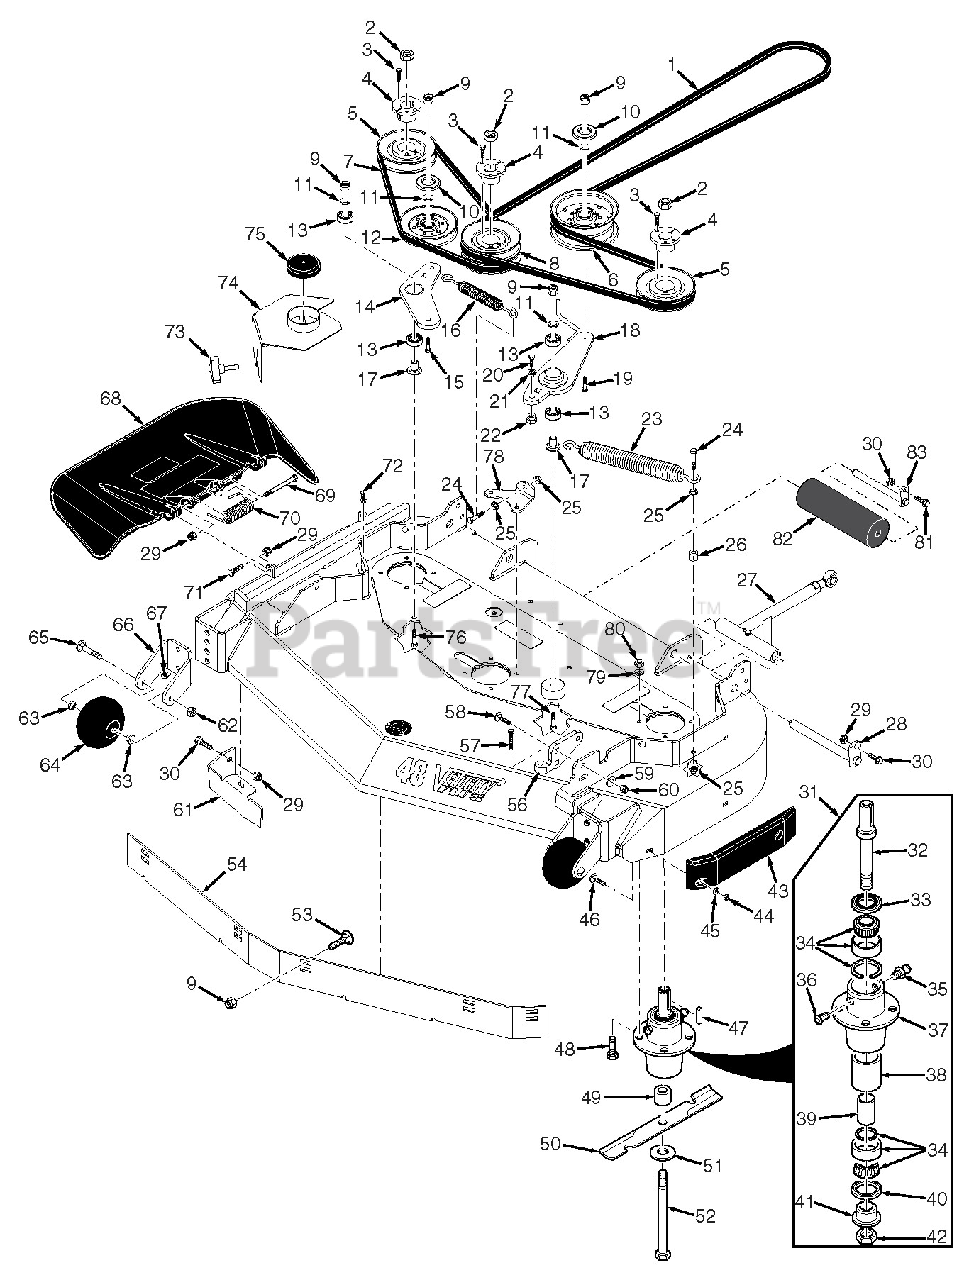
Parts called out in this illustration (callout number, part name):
1	Belt, Deck Drive
2	Nut, 5/8-11 UNC
3	Bolt, Hex Head 1/4-20 x 1"
4	Tapered Hub, 1.125" Bore
5	Pulley, 5.13" Dia.
5	Pulley, 5.73" Dia.
6	Pulley, 5" Idler
7	Belt, RH Deck Drive
8	Pulley, 5.232" Dia.
8	Pulley, 5.832" Dia.
9	Nut, Elastic Stop 3/8-16
10	Dust Shield
11	Flatwasher, 3/8-.391 x .938 x .105 HD
12	Pulley, Idler
13	Bearing
14	Idler Arm Assy.
15	Bolt, Hex Head 3/8-16 x 2"
16	Spring, RH Deck
17	Pivot, Idler
18	Idler Arm Assy.
19	Bolt, Hex Head 3/8-16 x 3"
20	Bolt, Hex Head 7/16-14 x 1"
21	Lockwasher, 7/16" Spring
22	Boss, Spring Anchor - LH
23	Spring, LH Deck
24	Bolt, Hex Head 3/8-16 x 1-1/2" Grade 8
25	Nut, Serrated Flange 3/8-16
26	Spacer
27	Pusharm Assy., LH
27	Pusharm Assy., RH
28	Rod Weldment, Pusharm
29	Nut, Elastic Stop 5/16-18
30	Bolt, Hex Head 5/16-18 x 1"
31	Spindle Assembly
32	Shaft, Spindle
33	Seal, Top
34	Bearing Assembly
35	Grease Fitting
36	Relief Fitting, Spindle
37	Spindle Housing
38	Spacer, Outside
39	Spacer, Inside
40	Seal, Bottom
41	Spindle Bushing
42	Nut, Special 1-1/16 - 18
43	Wear Pad
44	Nut, Center Lock 5/16-18
45	Flatwasher, 5/16-.344 x .688 x .065
46	Bolt, Carriage 5/16-18 x 3/4"
47	Key, 1/4 x 1/4 x 2"
48	Bolt, Hex Head 5/16-18 x 1-3/4" Grade 8
49	Spacer, Spindle Bottom
50	Cutter Blade, 16.5"
50	Cutter Blade, 18"
51	Flatwasher, 5/8-.688 x 1.75 x .134 HD
52	Bolt, Hex Head 5/8-11 x 9-1/2"
53	Bolt, Carriage 3/8-16 x 1"
54	Baffle, Flange - 48V
54	Baffle, Flange - 52V
55	Cutter Deck w/Decals
56	Lever Assy., Deck Level
57	Bolt, Deck Adjustment
58	Bolt, Carriage 7/16-14 x 1-1/4"
59	Flatwasher, 1/2-.531 x 1.062 x .095
60	Nut, Elastic Stop 7/16-14
61	Baffle, Turbo
62	Nut, Center Lock 3/8-16
63	Bushing, .376 ID Oilite
64	Wheel, Anti-Scalp
65	Bolt, Carriage 3/8-16 x 4"
66	Bracket, Anti-Scalp Wheel
67	Bolt, Serrated Flange 3/8-16 x 1"
68	Discharge Chute Assy.
69	Bolt, Hex Head 5/16-18 x 4-3/4"
70	Spring, Discharge Chute
71	Bolt, Hex Head 5/16-18 x 1-3/4"
72	U-Nut, 3/8-16
73	Wing Nut, 3/8-16
74	Belt Cover Assy., LH
74	Belt Cover Assy., RH
75	Cap, Spindle
76	Bolt, Hex Head 3/8-16 x 2-1/4"
77	Bolt, Hex Head 3/8-16 x 3-1/4"
78	Anchor Bracket, Spring
79	Lockwasher, 5/16" Spring
80	Nut, Elastic Stop 5/16-18 Grade 8
81	Bolt, Hex Head 5/16-18 x 1"
82	Guide Roller
83	Shaft Weldment, Guide Roller
